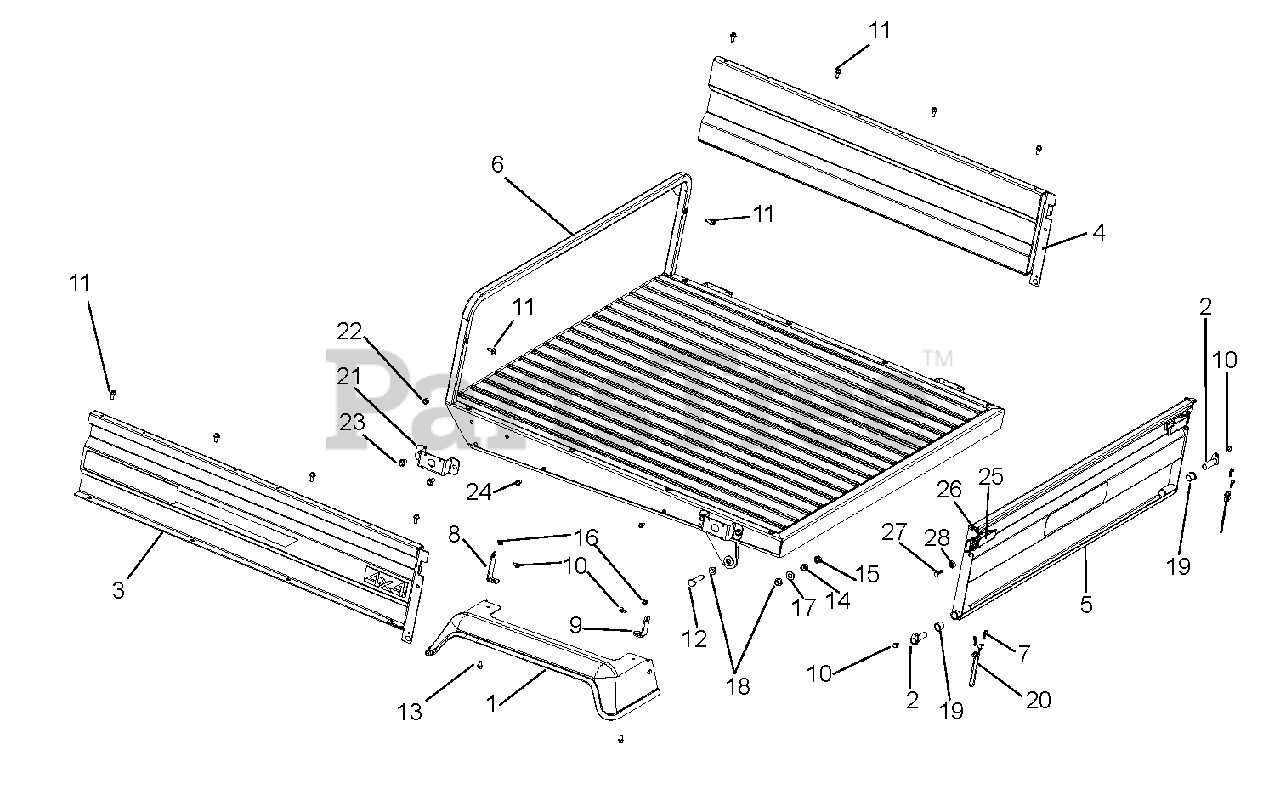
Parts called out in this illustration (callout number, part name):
1	FENDER BLACK UNIVERSAL TRUCK
2	WELDMENT, TAILGATE PIVOT
3	KIT, LEFT HAND BED SIDE 4 X 2 Includes Decals (996123, 125)
4	KIT, RIGHT HAND BED SIDE 4 X 2 Includes Decals (996123, 125)
5	KIT, TAILGATE Includes Decals, Latch & Bushings (996123, 125, 146)
6	BED BASE SUB-ASSEMBLY, BLACK
7	PIN, HAIR INTERNAL .08 X .18 X 1.18
8	BRACKET, FENDER MOUNT FRONT
9	BRACKET, FENDER MOUNT REAR
10	SCREW HEX SELF-TAP 1/4-20 X 1/2
11	BOLT, SERHFWH .312-18 X .75 YWZC
12	HFS 1/2-13 X 2 1/4 GR5 PLT
13	BOLT, SERHFWH .312-18 X .75 YWZC
14	NUT, LOCK CENTER .50-13 YWZC
15	NUT, JAM .50-13 GR5
16	NUT, LOCKING TOP FLANGE .25-20 YWZC
17	WASHER, FLAT STEEL .531 X 1.06 X .095 YWZC
18	BUSHING, 1/2ID X 5/8OD X 1/2 FLANGE
19	BUSHING, .75D X .625ID X 1.5L WITH FLG
20	TAILGATE CABLE
21	BRACKET, TREKER, STAKE POCKET
22	NUT, LOCKING NYLON .38-16 YWZC
23	BOLT, SERRATED HEX FLANGE WASHER HEAD .38-16 X .75
24	BOLT, SCREW HEX FLANGED WHIZ LOCK HEAD .25-20 X .62
25	LATCH, TAILGATE
26	SPACER, LATCH
27	BOLT-ROUND HEAD SQUARE NECK 10-24X.75 GRADE 5 Y
28	NUT-LOCKING-NYLON 10-24 With insert
